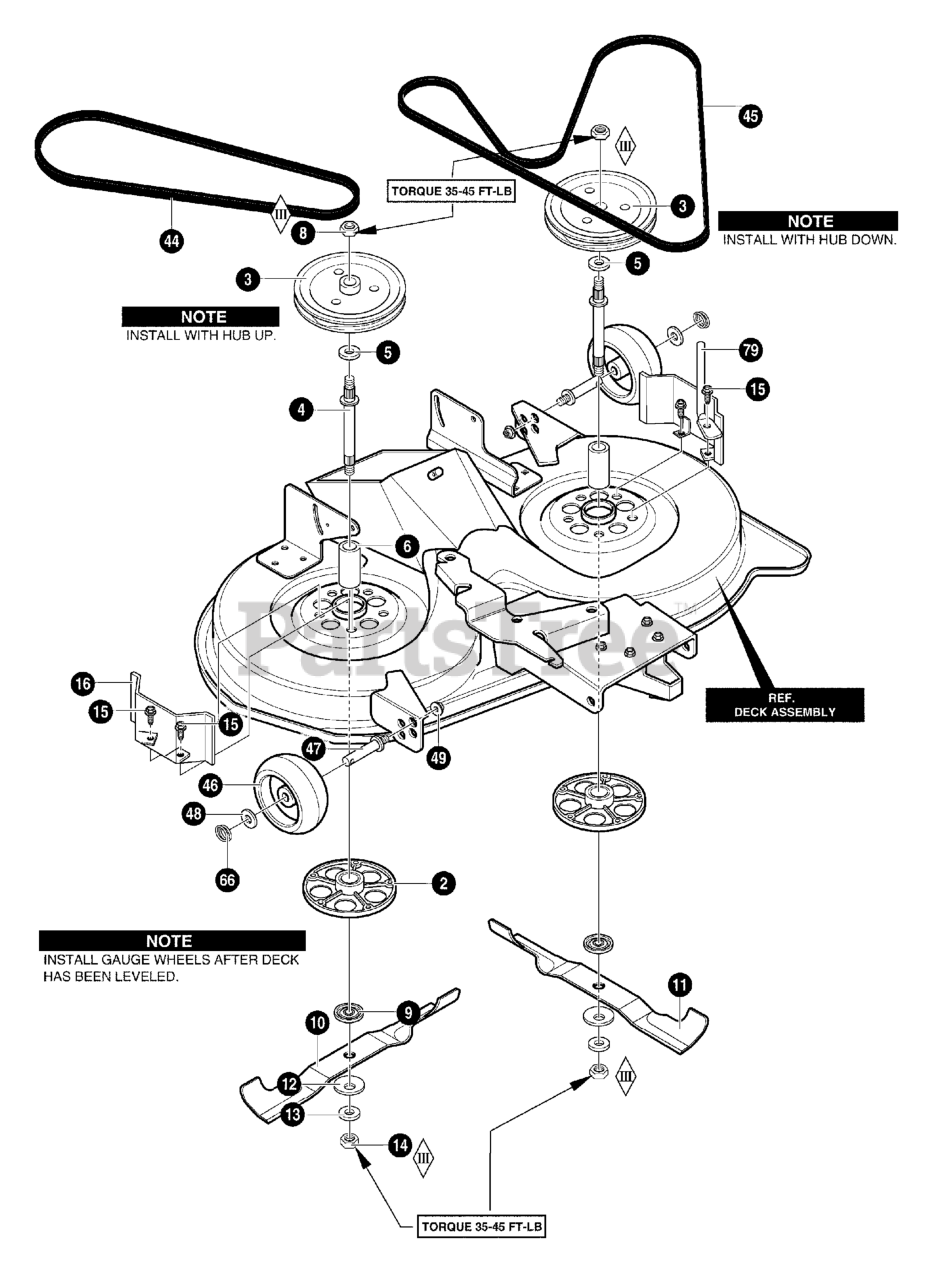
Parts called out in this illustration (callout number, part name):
2	ASM. JACKSHAFT HOUSING W/VENTS
3	PULLEY, DECK
4	JACKSHAFT 7.76LG-9/16-18TH
5	WASHER, FLAT .625X1.00X.188
6	SPACER, .625X.875Z1.91
8	NUT, 9/16-18 CTRLK
9	ADAPTER, DECK/BLADE
10	BLADE LH
11	BLADE RH
12	WASHER, BELLVIL .625X1.75
13	WASHER, FLAT .625X1.00X.188
14	NUT, 9/16-18 CTRLK
15	SCREW, 3/8-16 x 1.00
16	PULLEY COVER
44	BELT V46.5LG
45	BELT, V
46	WHEEL, GAUGE
47	BOLT,HHSH 3/8-16X.63
48	FLATWASHER, .518X.87X.16
49	NUT, 3/8-16 HWDFLLK WHIZ
66	CIRCLE PIN
79	ZINC ROD BELT GUIDE
